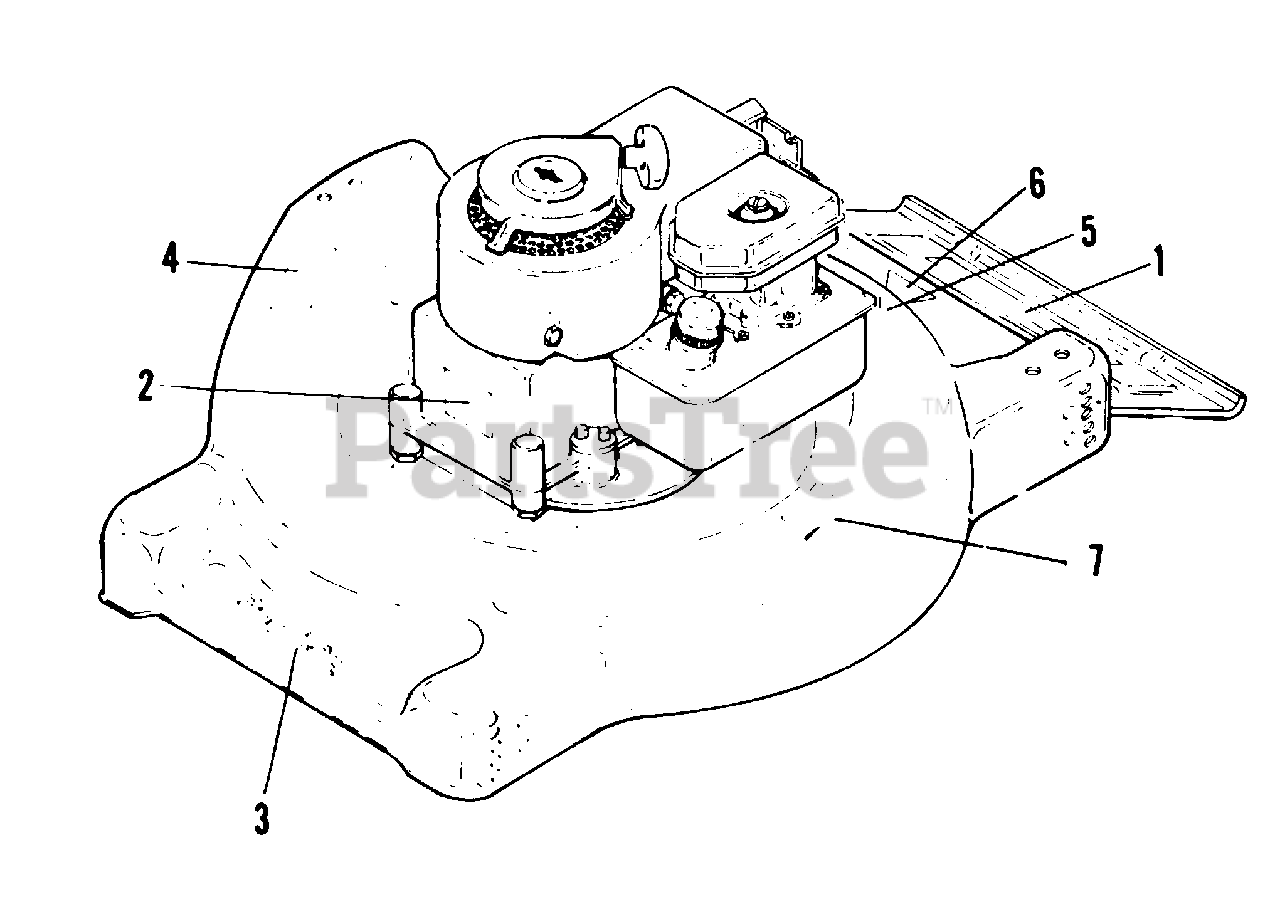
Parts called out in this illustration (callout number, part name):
1	DECAL, Zipper
2	DECAL, 20"
3	FlLM, "Simplicity"
4	DECAL, "Bag in Place"
5	DECAL, O.P.E.I.
6	DECAL, Caution
7	DECAL, "Place Foot . . ."
